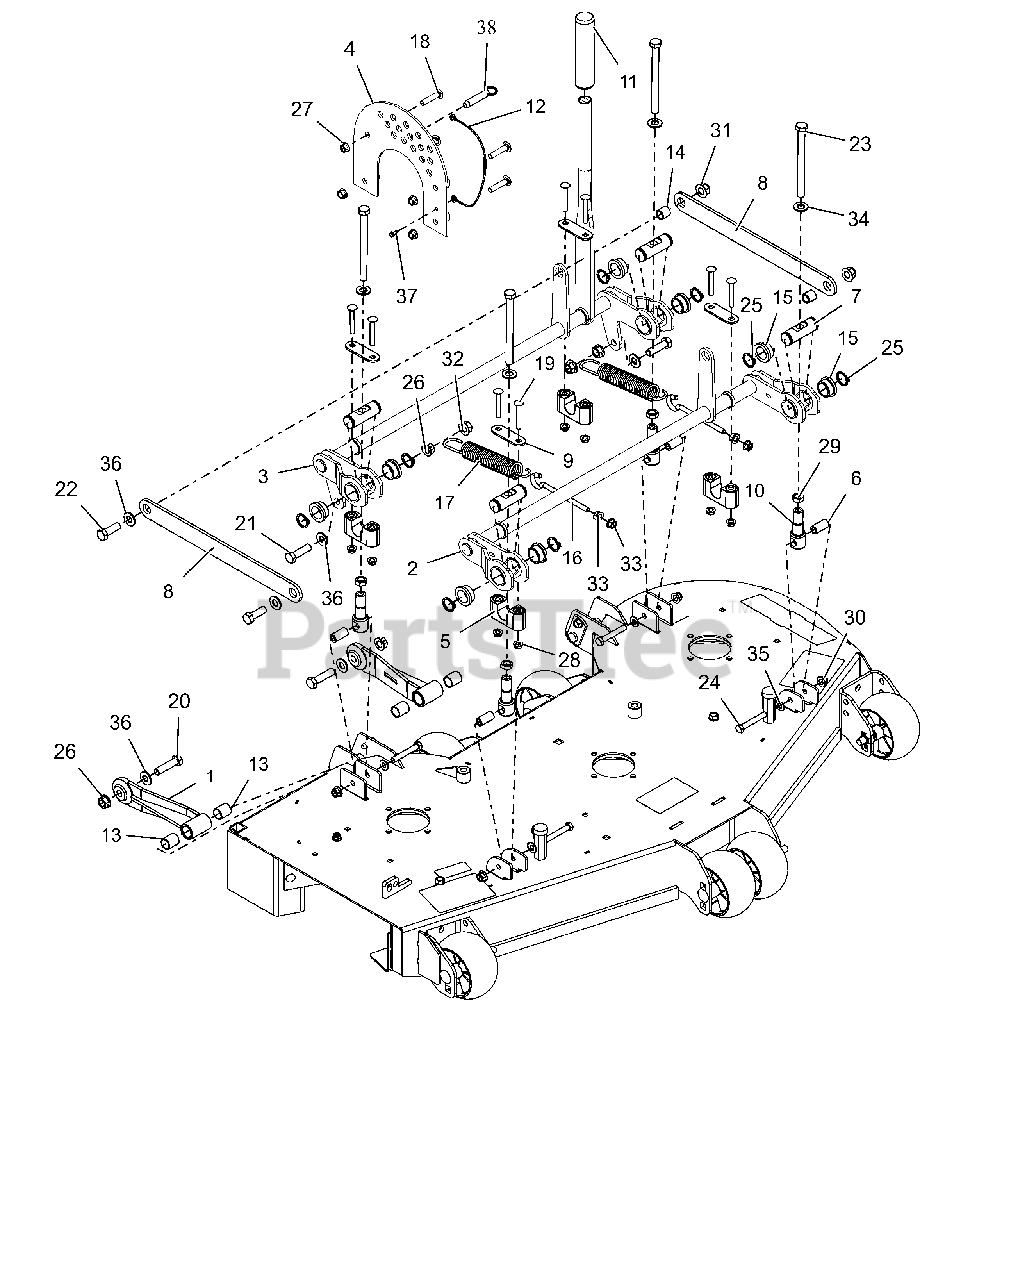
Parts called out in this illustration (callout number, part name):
1	WLDMT, PUSHER LINK BAR (BLACK)
2	WLDMT, DECK LIFT
3	WLDMT, DECK LIFT
4	WLDMT, DECK INDEXING (RED)
5	ASM-BUSHING, DECK LIFT
6	SPACER, DECK LEVELING
7	PIN, DECK LIFT
8	LINK, DECK LIFT (BLACK)
9	PLATE, BEARING SUPPORT
10	LINK, DECK LIFT FORMED
11	GRIP, DECK LIFT
12	CABLE, 12.0 LANYARD, NYLON
13	BRG, .750 X .875 X 1.000
14	BSHG, SLV .510 X .751 X .750
15	BSHG,FLG 1.0 X 1.25 X 1.5 X .6
16	BOLT,.38-16 X 4.25-.62 DIA EYE
17	SG-TENS .162X1.25X8.25 WLD 25
18	BLT-RHDSSQNK .38-16X1.75 G5YZ
19	BLT-RDHDSQSHNK .31-18X2.25 YWZ
20	BLT-HEX .500-13X2.00 GR8 YWZC
21	@BLT-HEX .50-13X1.75 GR5 YWZC
22	@BLT-HEX .50-13X1.50 GR5 YWZC
23	BOLT,.50-13X6.00-2.50 LG THD
24	@BLT-HEX .38-16X2.50 GR5 YWZC
25	RG-RTNG-EXT 1.00X.078
26	NUT-LK-CTR-FLG .50-13 YWZC
27	NUT-LK-CTR-FLG .38-16 YWZC
28	@NUT-LK-CTR-FLG .31-18 YZ GR F
29	NUT-JAM .50-13 YWZC
30	@NUT-LK-NYL-FLG .38-16 YWZC
31	@NUT-LK-NYL-FLG .50-13 YWZC
32	NUT-SPNLK-FLG .50-13 YWZC
33	@NUT-SPNLK-FLG .375-16 YWZC
34	FLATWASHER 1/2 SAE HARD 15906
35	@WSHR-FL-STL.406X.812X.065 YWZ
36	@WSHR-FL-STL.531X1.06X.095YWZC
37	@SCR-TAP 10-24X.50 HWH TR YWZC
38	PIN, .500 x 2.000 USABLE LG BALL
